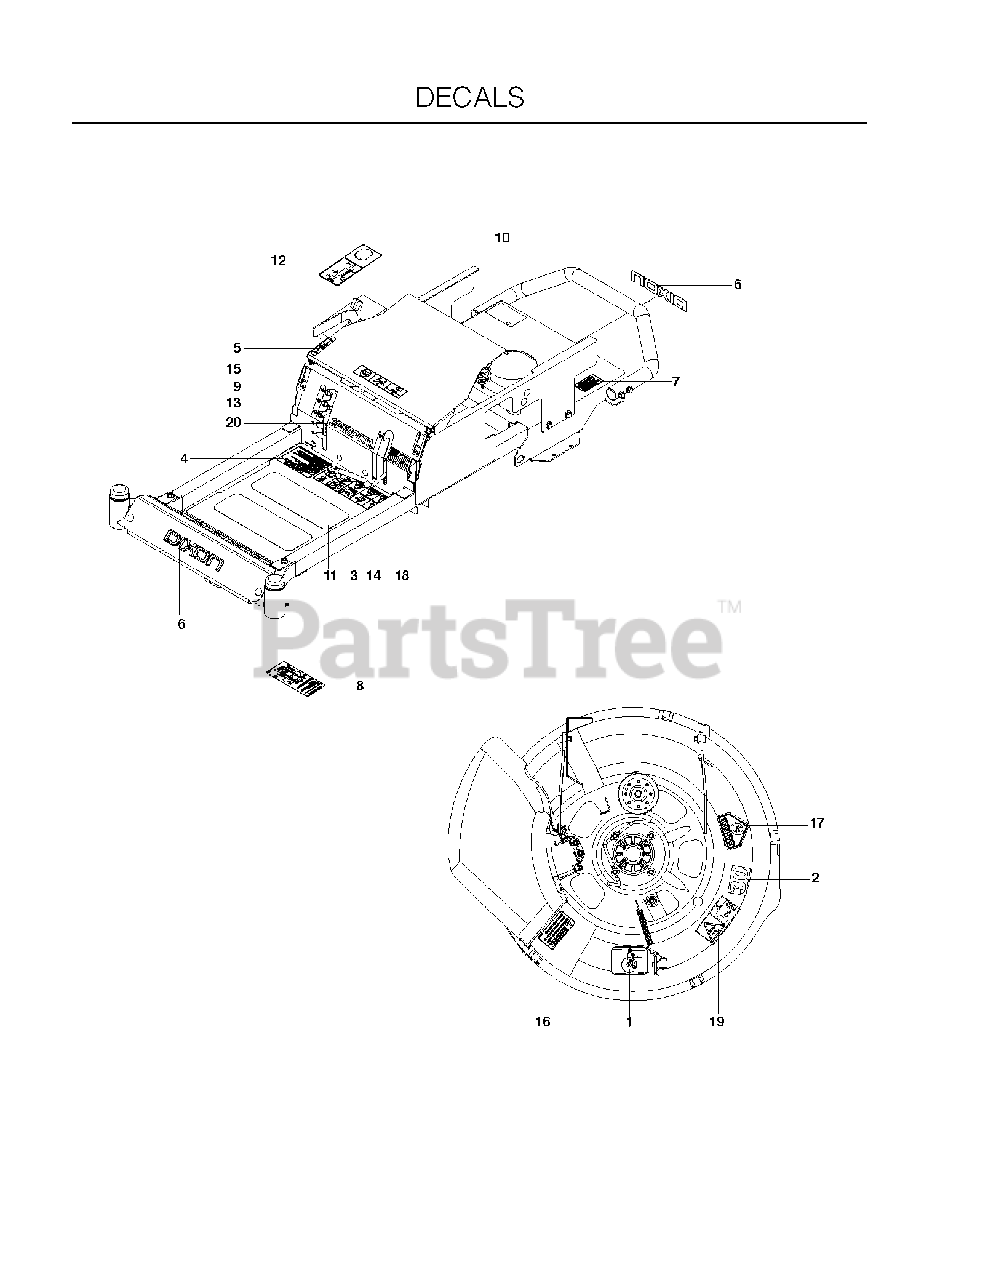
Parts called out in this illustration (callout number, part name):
1	DECAL, BELT ROUTING
2	DECAL, 30"
3	DECAL, SAFETY WARNING
4	DECAL, WARNING
5	DECAL, PARK BRAKE
6	DECAL, DIXON LOGO, DOMED
7	DECAL, PROP. 65
8	DECAL, SERVICE
9	DECAL, BATTERY
10	DECAL, DO NOT MOUNT
11	ANTI-SKID PAD
12	DECAL, CONTROL PANEL
13	DECAL, DECK HEIGHT
14	DECAL, BLADE ENGAGEMENT
15	DECAL, MOTION CONTROL
16	DECAL, CAUTION
17	DECAL, CPSC
18	DECAL, FLAG
19	DECAL, EURO SEVERING
20	DECAL, SPEEDZTR 6.5"
